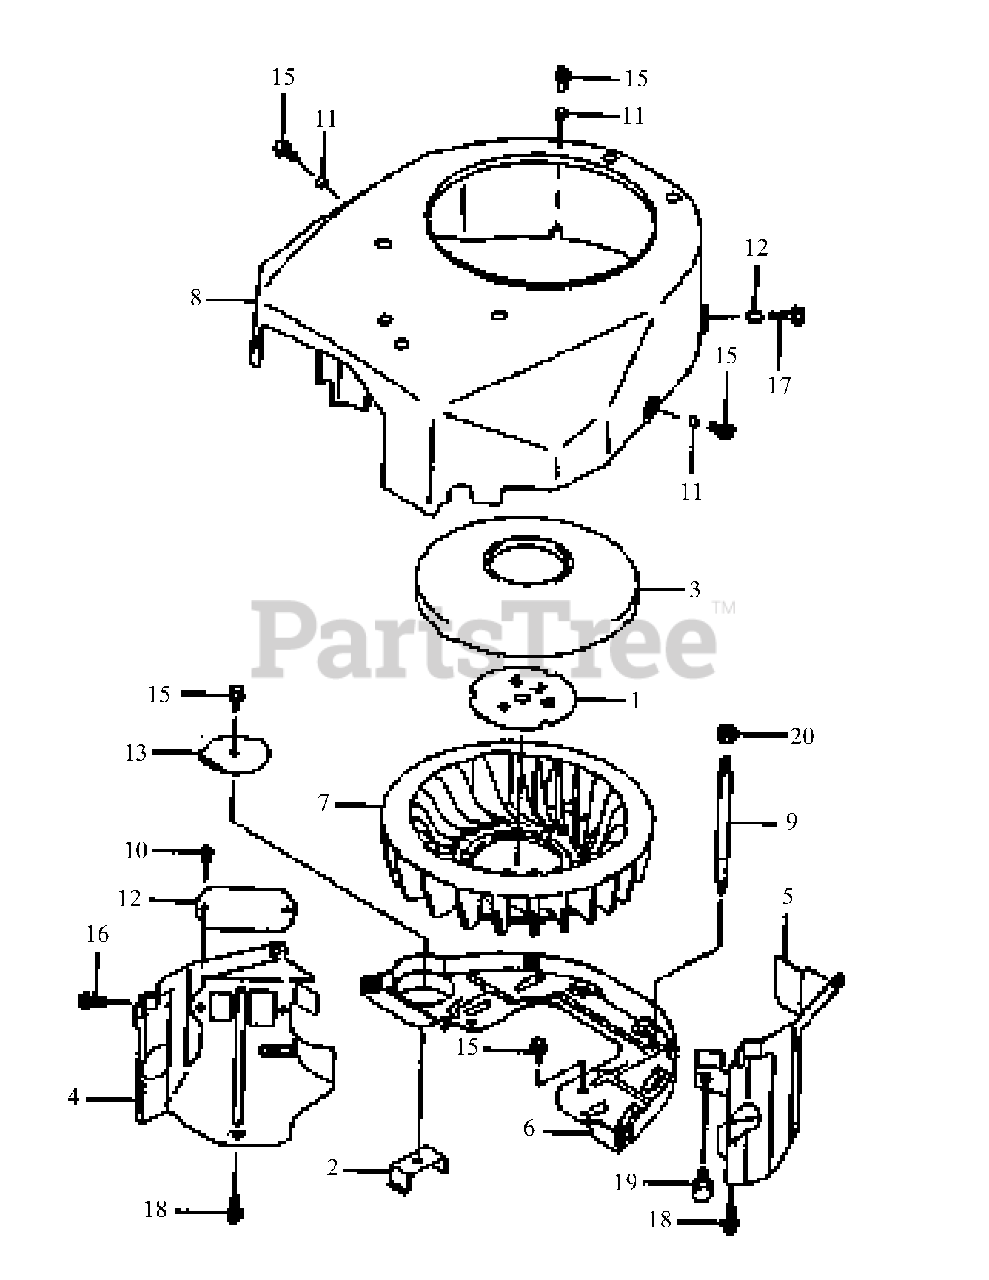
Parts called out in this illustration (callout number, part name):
4	Shroud, Engine
5	Shroud, Engine
6	Shroud, Engine
7	Fan
11	Spacer, 6.2x7.9x5
12	Spacer 6.5x7.9x10.5
15	Bolt, Flange
16	Bolt, Flange
17	Bolt, Flange
18	Bolt, Flange
19	Bolt, Flange
